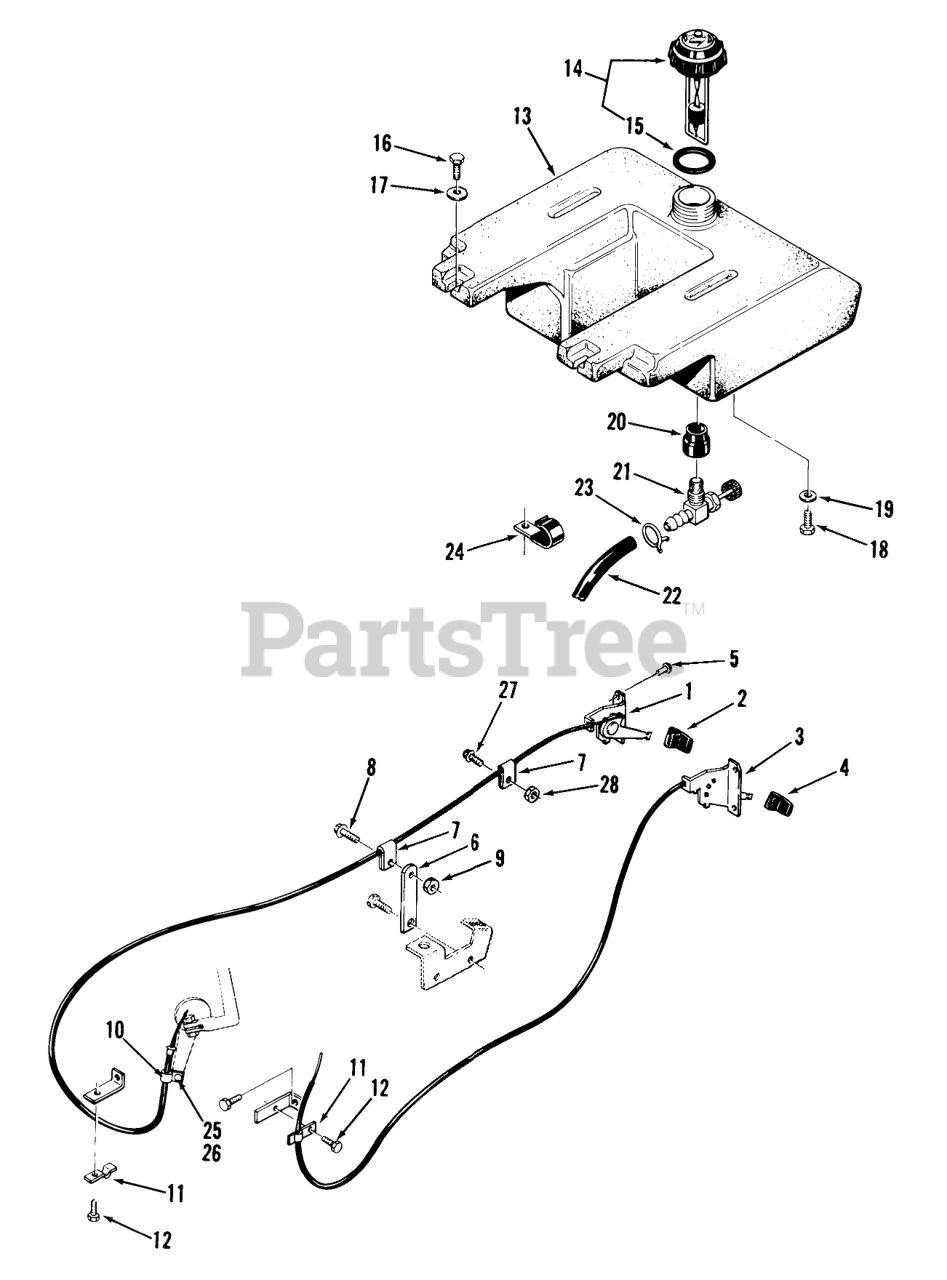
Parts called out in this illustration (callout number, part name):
1	Throttle Control C-105, C-125, C-145, C-165 Only
1	CONTROL-THROTTLE
2	KNOB-THROTTLE
2	CONTROL-CHOKE
3	CONTROL-CHOKE
4	KNOB-CHOKE
5	RIVET-4
6	Strap
7	THROTTLE CONTROL CLP
8	Screw
9	Nut
10	Clip
11	CLAMP-CABLE
12	SCREW
12	Screw #10-24 X 3/8 C-81 Only
13	TANK-FUEL
14	ASSY-GAUGE CAP
15	GASKET-GAS CAP
16	Bolt
17	Washer
18	Bolt
19	Lockwasher
20	BUSHING
21	VALVE-FUEL
22	Fuel Line
22	Fuel Line C-85 Only
23	Clamp
24	CLIP
25	Screw
26	Nut
27	Screw
28	Nut
